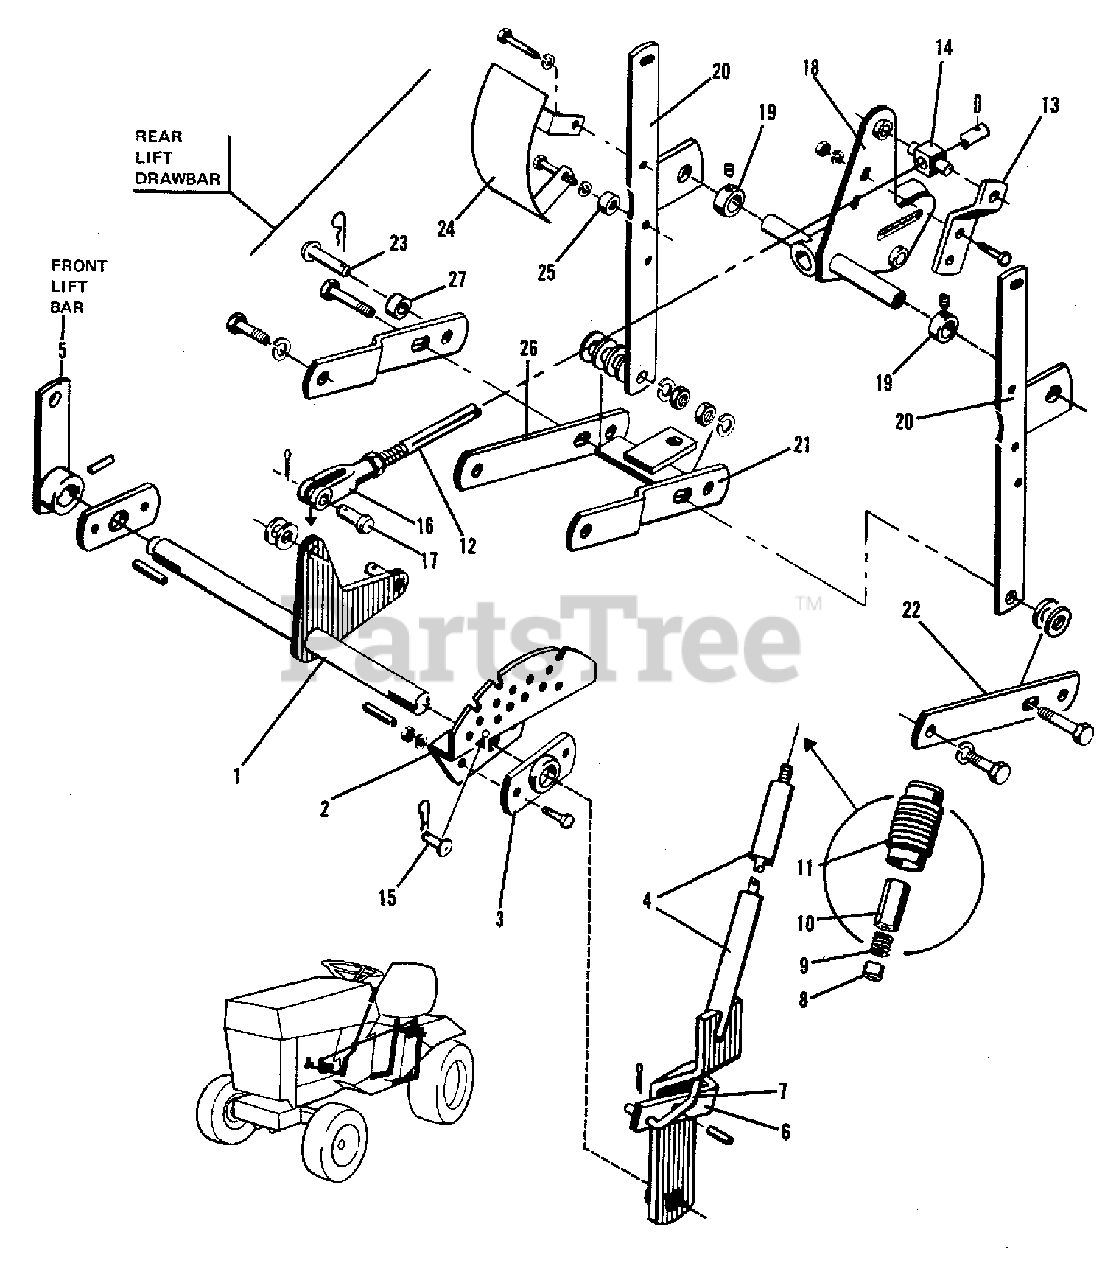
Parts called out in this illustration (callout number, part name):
1	SHAFT ASSEMBLY, Lift
2	QUADRANT, Lift Lever (L.H.)
3	BEARING, Lift Lever
3	LOCKWASHER, 3/8
3	NUT, 3/8 NC
3	CAPSCREW, 3/8 NC x 1-1/4
3	CAPSCREW, 3/8 NC x 1-1/2
4	LEVER, Lift (L.H.)
4	KEY, Parallel, 1/4 x 1/4 x 1-1/4
4	SETSCREW, Socket Head, 5/16 NC x 5/16
5	LEVER, Front Lift
5	SETSCREW, Socket Head, 5/16 NC x 5/16
6	LATCH, Lift Lever
6	PIN, Spring, 3/8 x 1
7	ROD, Latch Lift lever (L.H.)
7	PIN, Cotter, 3/32 x 1
8	SPACER, Lift Lever Handle
9	SPRING, Standard
10	BUTTON, Thumb
11	GRIP, Lift Lever
12	ROD, Lift (Manual)
12	NUT, Jam, Hex., 1/2 NF
13	SUPPORT, Swivel
13	CAPSCREW, 3/8 NC x 1
13	LOCKWASHER, 3/8
13	NUT, 3/8 NC
13	WASHER, Plain, 7/8 x 14 Ga.
14	PIN, Spring, 3/16 x 3/4
15	PIN, Lock
15	PIN, Quick
16	YOKE, Rod End, 1/2 NF
17	PIN, Yoke, 1/2
17	PIN, Cotter, 1/8 x 1
17	WASHER, Plain, 9/16 x 1 x 12 Ga.
18	LEVER ASSEMBLY, Lift
19	COLLAR, Set
19	SETSCREW, Socket Head, 5/16 NC x 5/16
20	ARM ASSEMBLY, Drawbar
20	CAPSCREW, 7/16 NC x 1
20	CAPSCREW, 7/16 NC x 1-1/4
20	CAPSCREW, 7/16 NC x 1-1/2
20	LOCKWASHER, 7/16 Medium
21	DRAWBAR ASSEMBLY
21	CAPSCREW, 7/16 NC x 1-1/4
21	CAPSCREW, 7/16 NC x 1-3/4
21	WASHER, 1/2 x 1-1/4 x 14 Ga. (Use as Required)
21	LOCKWASHER, 7/16
21	CAPSCREW, 7/16 NC x 2-1/4
21	NUT, Hex, 7/16 NC
22	BAR, Pull
23	PIN, Round Head
23	PIN, Quick
24	GUARD ASSEMBLY, Pulley
